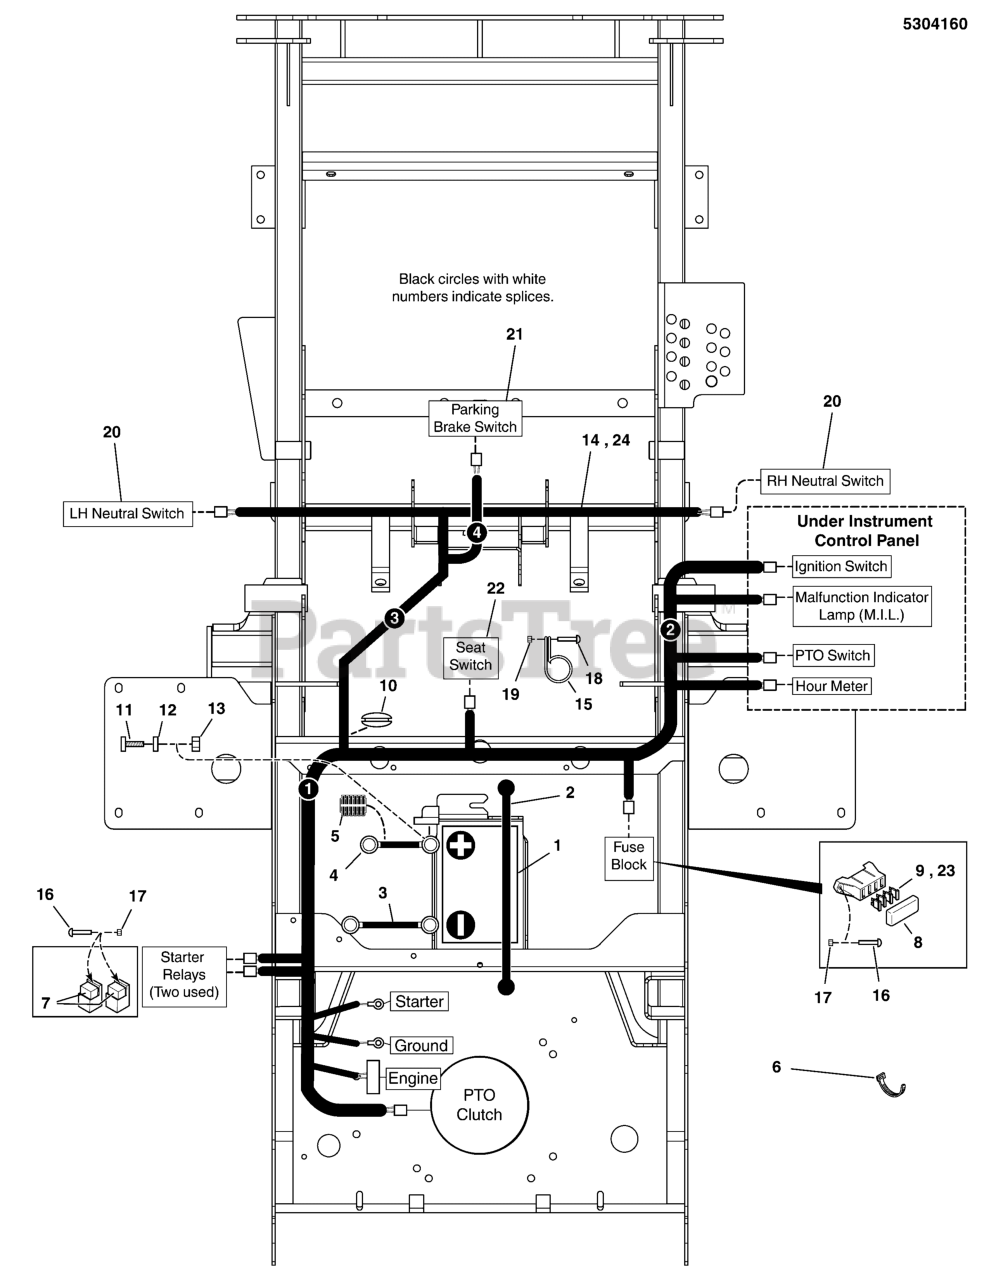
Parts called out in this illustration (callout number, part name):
1	BATTERY, WET ( BCIU1, 350 CCA)
2	STRAP-BLACK RUBB
3	BATTERY CABLE, NEG, 22, 1/4-5/16
4	BATTERY CABLE, POS, 22, 1/4-5/16
5	WIRE LOOM, 3/8 ID X 16 IN
6	TIE, SELF-LOCKING, 12"
7	RELAY, 12V, 40A
8	COVER, VINYL FUSEBLOCK
9	FUSE, ATO, 20 AMP
10	GROMMET, 1-1/2" ID FOR 1/4" METAL
11	BOLT, 1/4-20 X 3/4 GD5 CZ
12	WASHER, 1/4 SAE
13	NUT, 1/4-20 HEX NYLOCK FLANGE
14	WIRE HARNESS, BVE37, IS3200
15	CLAMP, VINYL INSULATED
16	SCREW, #10-24 X 3/4 ROUND PHILLIPS
17	NUT, #10-24 HEX NYLON LOCK
18	SCREW,1/4-20X1,ZINC PHOS & OIL
19	NUT, 1/4-20 HEX SERR. FLANGE
20	SWITCH, PLUNGER, NO, SINGLE POLE SNAP-IN
21	SWITCH, LOW PROF, NC/NO
22	SWITCH, PLUNGER, N.C.
23	FUSE, ATO-15 (15 AMP)
24	WIRE HARNESS, 28HP B&S EFI, IS2100Z/IS3200Z
